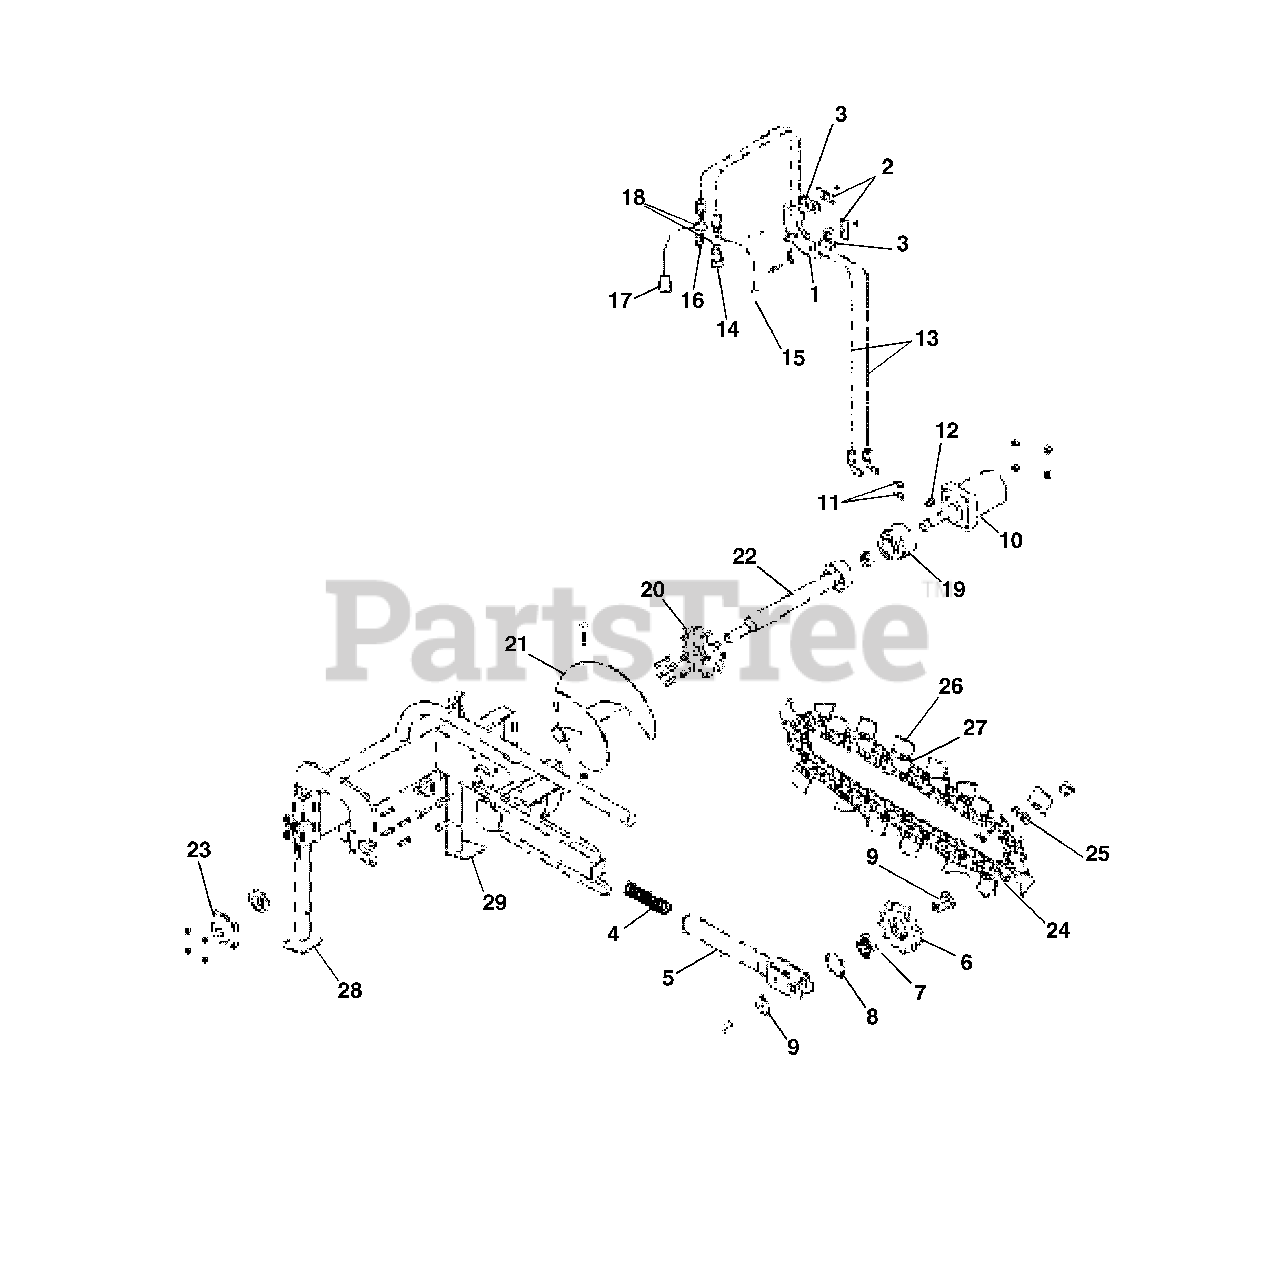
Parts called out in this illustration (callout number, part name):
1	Bracket, Attachment Hose-Assembly
2	Plate, Cover
3	Clamp, Dual Hose .50 ID
4	Spring, Compression
5	Boom, Inside
6	Sprocket, Idler
7	Bearing, Square Bore
8	Ring-Retaining-Internal 3.52 x .109
9	Shaft, Square Idler
10	Motor, Hydraulic
11	Fitting, Hydraulic Straight
12	Key-Woodruff .31 x 1.00
13	Hose, Hydraulic
14	Coupling, Female Quick
15	Plug, Dust .50 Quick Coupler
16	Coupler, Male Quick
17	Cap, Dust .50 Quick Coupler
18	Seal, Bonded
19	Hub, Drive
20	Sprocket, Drive
21	Flight, Auger
22	Shaft, Auger
23	Bearing, Square Flange
24	Chain, 13 Station - with Teeth
24	Chain, 13 Station (Chain Only) without Teeth
24	Chain, 26 Station - with Teeth
24	Chain, 26 Station (Chain Only) without Teeth
25	Spacer, 1.00 Tooth
25	Spacer, .50 Tooth
26	Tooth, Left Hand
27	Tooth, Right Hand
28	Leg, Trencher Support - Right Hand
29	Leg, Trencher Support - Left Hand
